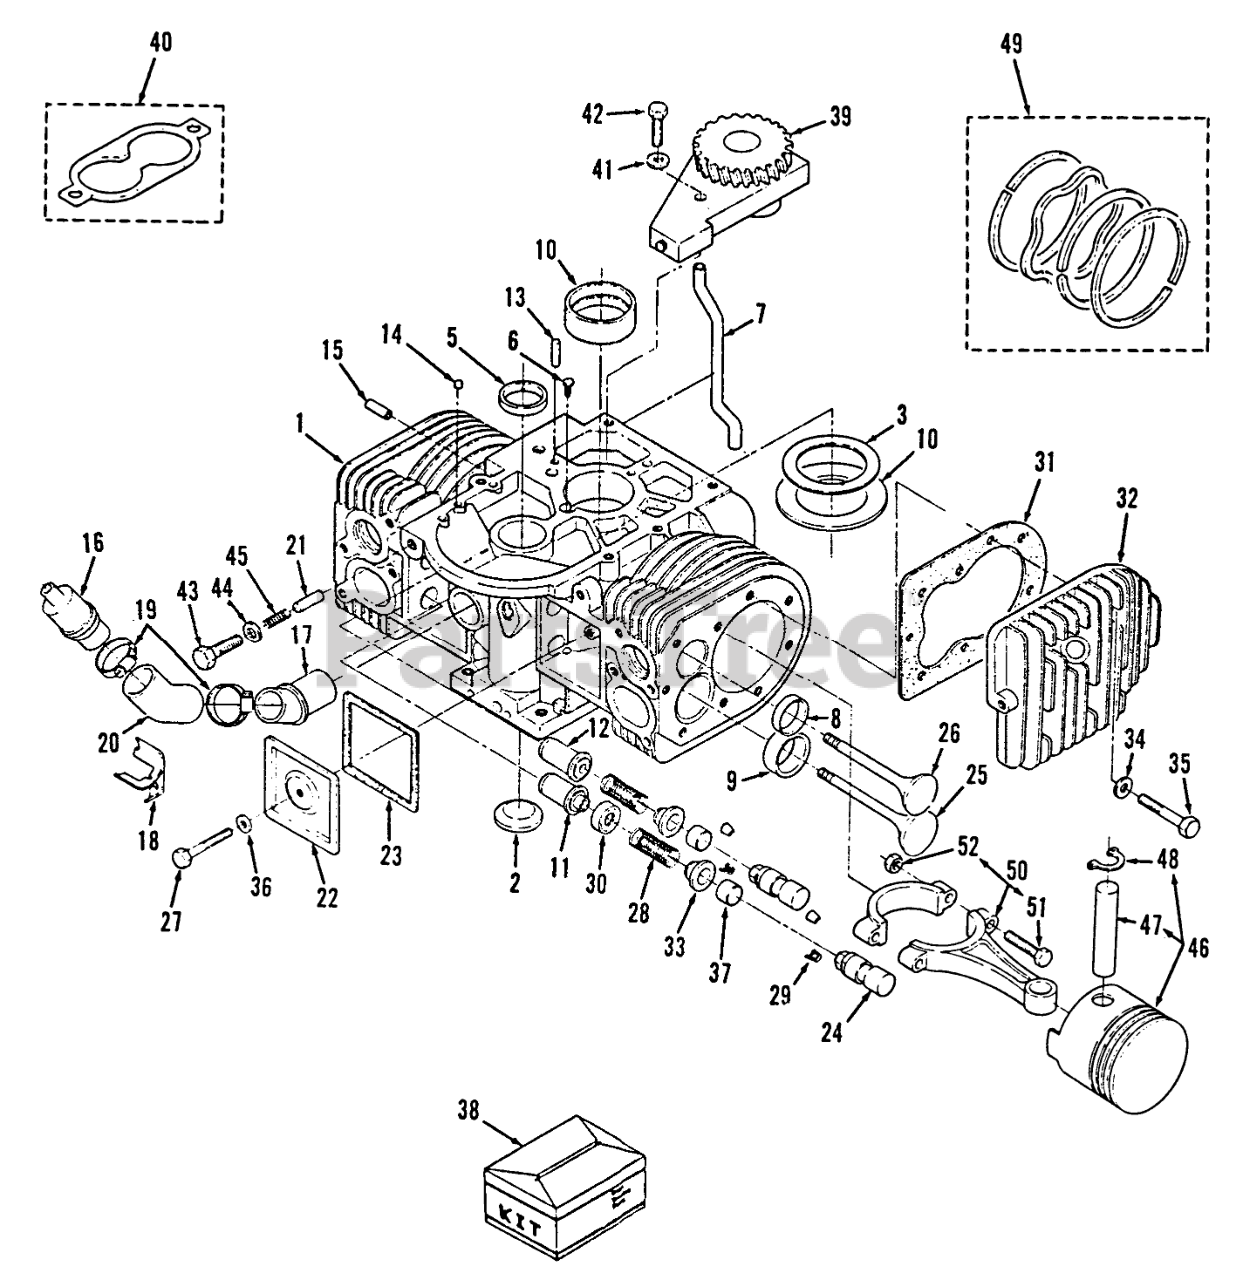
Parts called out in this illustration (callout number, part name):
2	Plug
3	Shim 0.005"
5	Camshaft Brg
6	Screw
7	Oil Tube
8	Standard
8	.002" Oversize
8	.005" Oversize
8	.010" Oversize
8	.025" Oversize
9	Standard
9	002" Oversize
9	005" Oversize
9	010" Oversize
9	025" Oversize
10	Standard
10	.002" Undersize
10	.010" Undersize
10	.020" Undersize
10	.030" Under
11	Guide-Intake Valve
12	Guide-ExhaustValve
13	Pin
14	Plug
15	Vacuum Tube
16	Breather Tube
17	BREATHER-ADAPTER
18	BREATHER-MTG BRKT
19	Hose Clamp
20	BREATHER-HOSE
21	DOWEL-PIN PLUG
22	Cover-Valve
23	Gasket
24	Tappet
25	Intake Valve
26	Exhaust Valve
27	HHCS 1/4-20 X 1 3/4
28	Spring
29	VALVE SPRING LOCK
30	Seal
31	Gasket
32	Side-Left
32	Right Side
33	Washer
34	Washer
35	Bolt
36	Washer
37	Cap-Valve
38	Pump-Oil
38	Kit-Oil Pump Gasket
39	OIL-PUMP
40	Oil Tube
41	Washer
42	Bolt
43	Bolt
44	Washer
45	Spring
46	Piston Pin & Retaining Rings-STD
46	Piston Pin & Retaining Rings-.005"
46	Left Side
46	Piston Pin & Retaining Rings-.020"
46	Piston Pin & Retaining Rings-.030"
46	Piston Pin & Retaining Rings-.040"
47	Pin-Piston
48	Retaining Ring
49	Standard
49	.005" Oversize
49	.010" Oversize
49	.020" Oversize
49	.030" Oversize
49	Piston Ring Set.040" Oversize
50	CONNECTING ROD W/NUT
51	Rod Bolt
52	Nut
